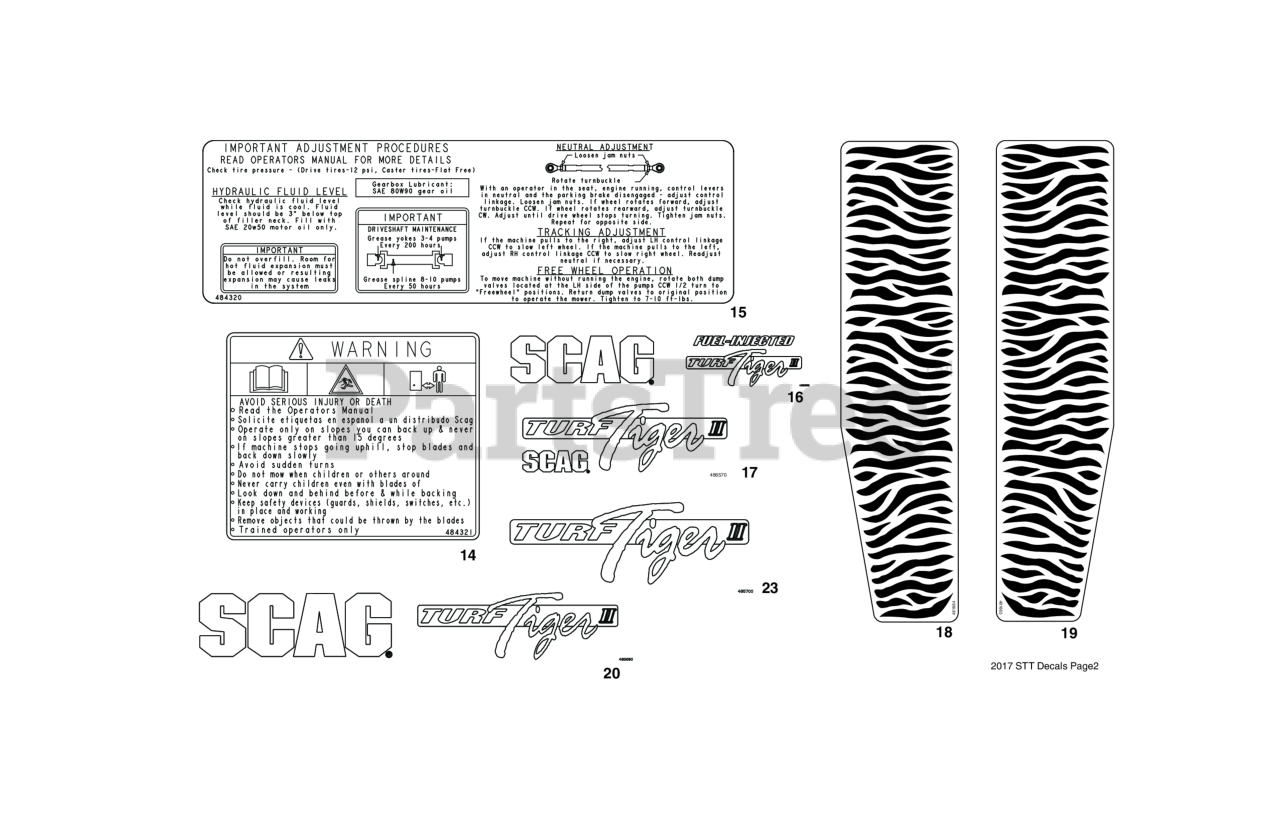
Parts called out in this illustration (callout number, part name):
14	Decal, Start/Drive Procedure
15	Decal, Checks and Adjustments
16	Decal, Hood - STTII Fuel Injected
17	Decal, Turf Tiger II
18	Decal, Stripes-RH
19	Decal, Stripes-LH
20	Decal, Hood - STTII
23	Decal, Turf Tiger II
